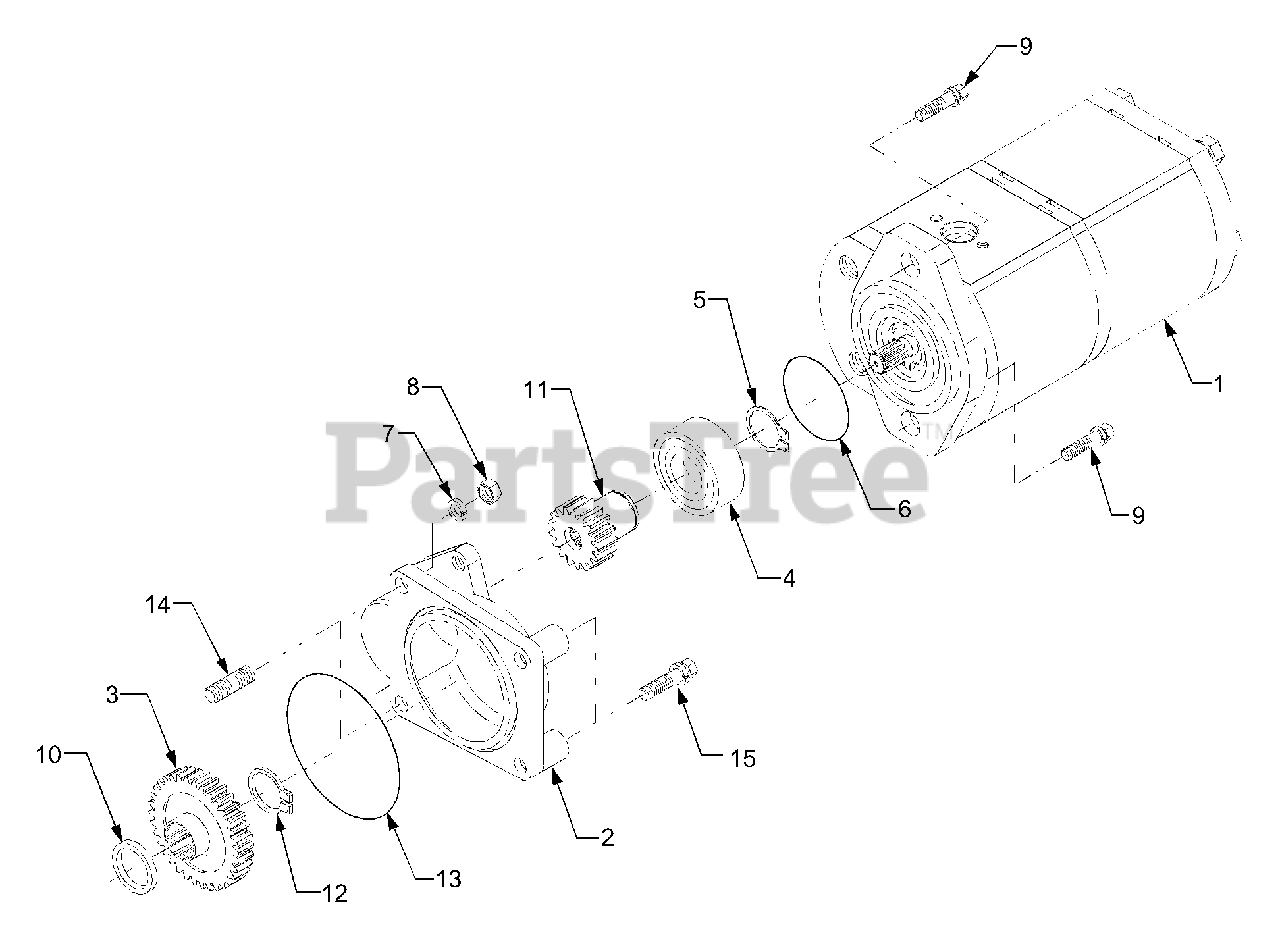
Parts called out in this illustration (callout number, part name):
1	Pump, Gear
2	Holder, Gear Pump
4	Bearing, Ball
5	Cir-clip, External
7	Washer, Spring
